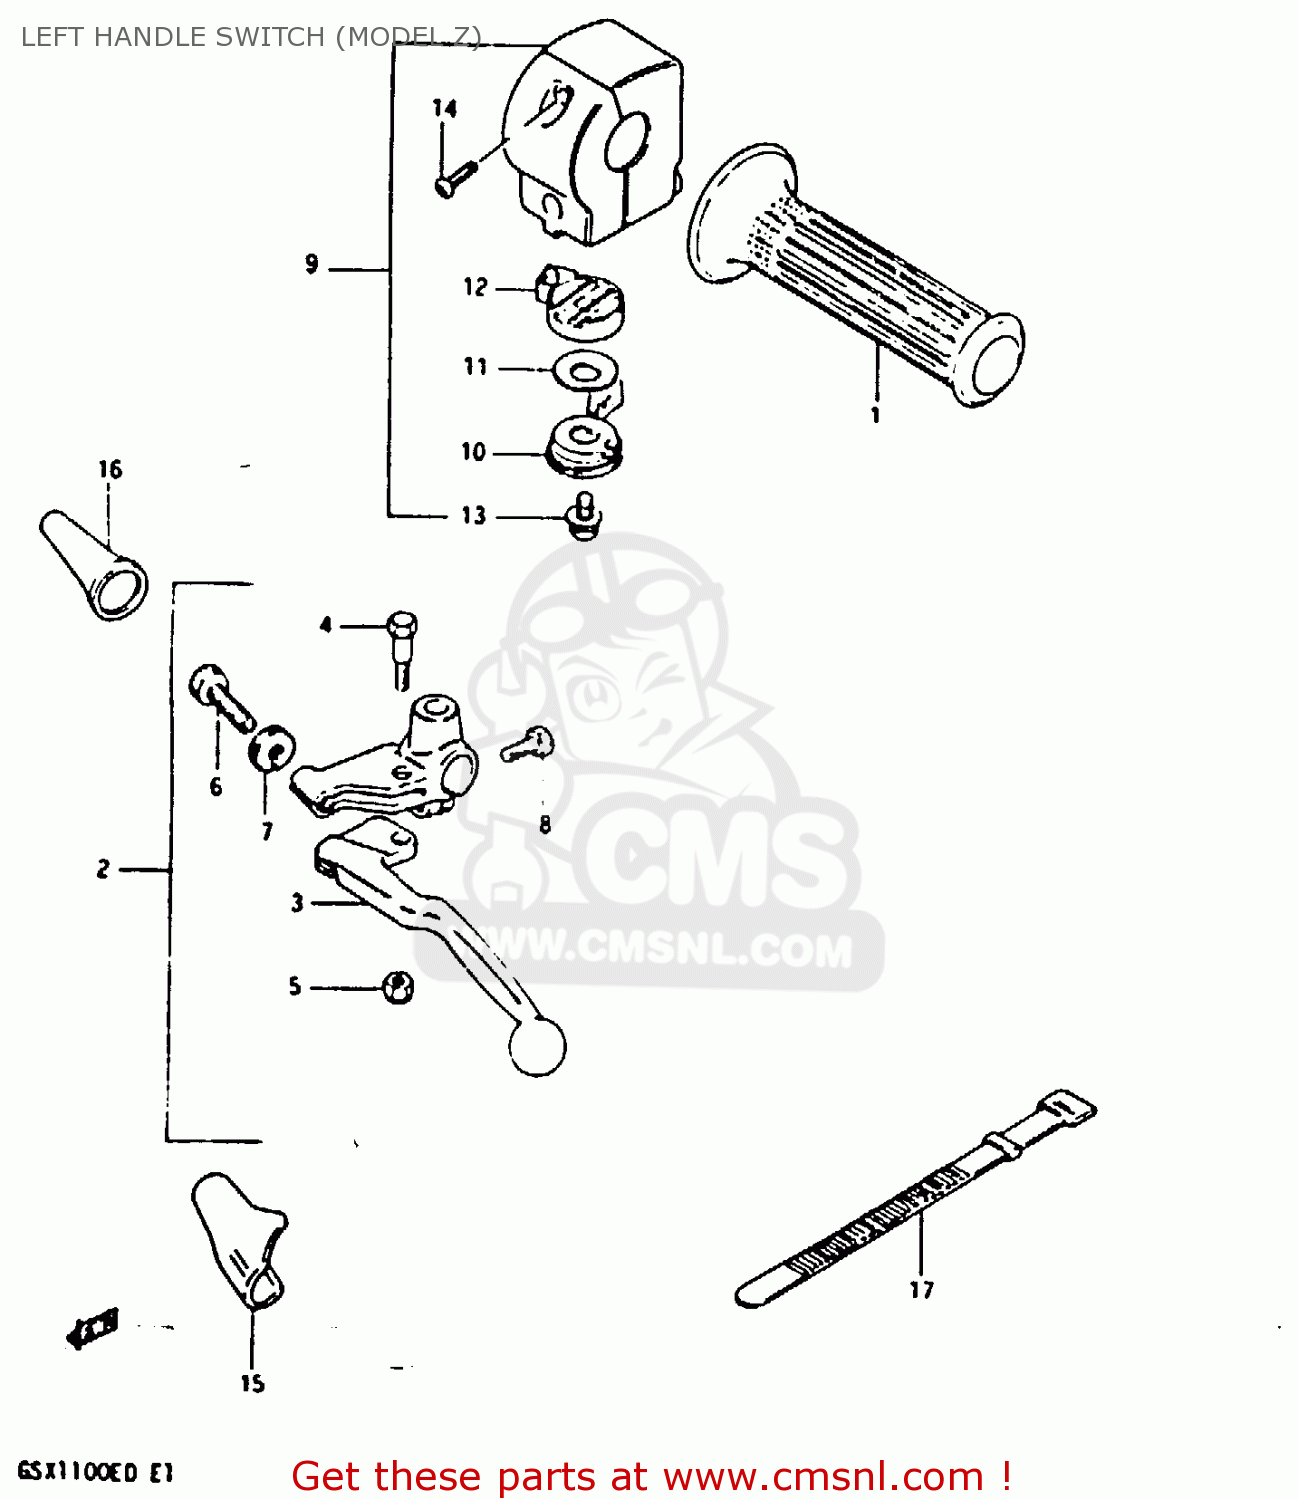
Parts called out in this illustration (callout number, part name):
1	GRIP,LEFT
2	LEVER ASSEMBLY
3	LEVER,CLUTCH
4	BOLT,LEVER
5	NUT 6MM
6	ADJUSTER,CABLE
7	NUT,CABLE ADJUSTER
8	BOLT
9	SWITCH ASSY, HANDLE LH
10	LEVER,STARTER
11	WASHER,ADJUSTER
12	BODY,CHOCK
13	SCREW,CHOKE LE
14	SCREW
15	COVER,CLUTCH LEVER
16	BOOT,CLUTCH CABLE
17	CLAMP(L:120)
